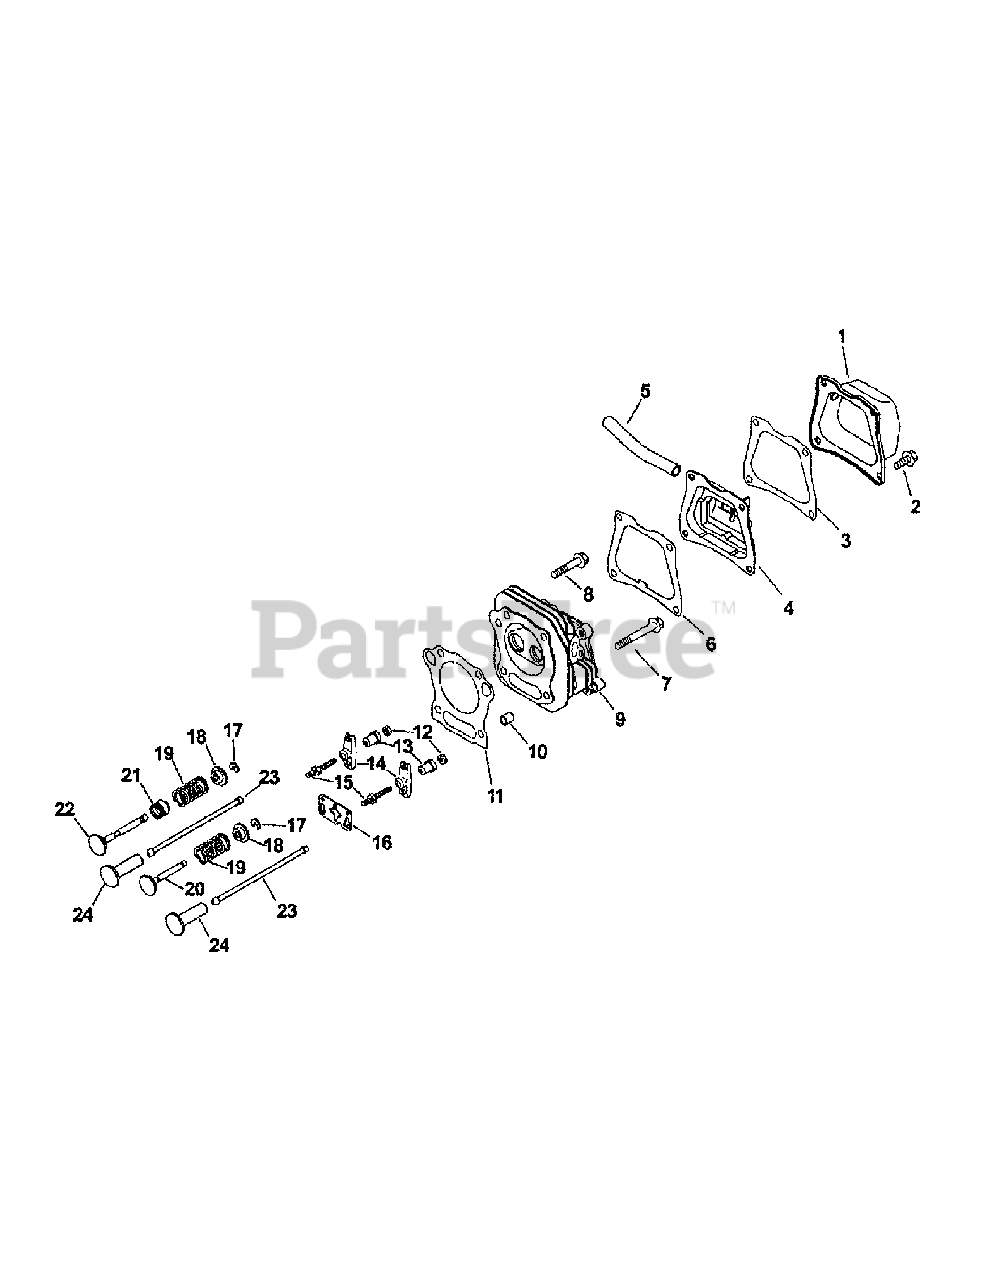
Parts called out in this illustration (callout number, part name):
2	Screw, Valve Cover
3	Gasket, Breather
4	Breather Assembly
5	Hose, Breather
6	Gasket, Breather
7	Screw, Cylinder Head
8	Screw, Cylinder Head
9	Head, Cylinder
11	Gasket, Cylinder Head
13	Pivot, Rocker Arm
15	Screw, Valve Adj.
16	Guide, Push Rod
17	Keeper, Valve
18	Cap, Valve Spring
19	Spring, Valve
20	Valve, Intake
21	Seal, Valve Stem
22	Valve, Exhaust
24	Lifter, Valve
